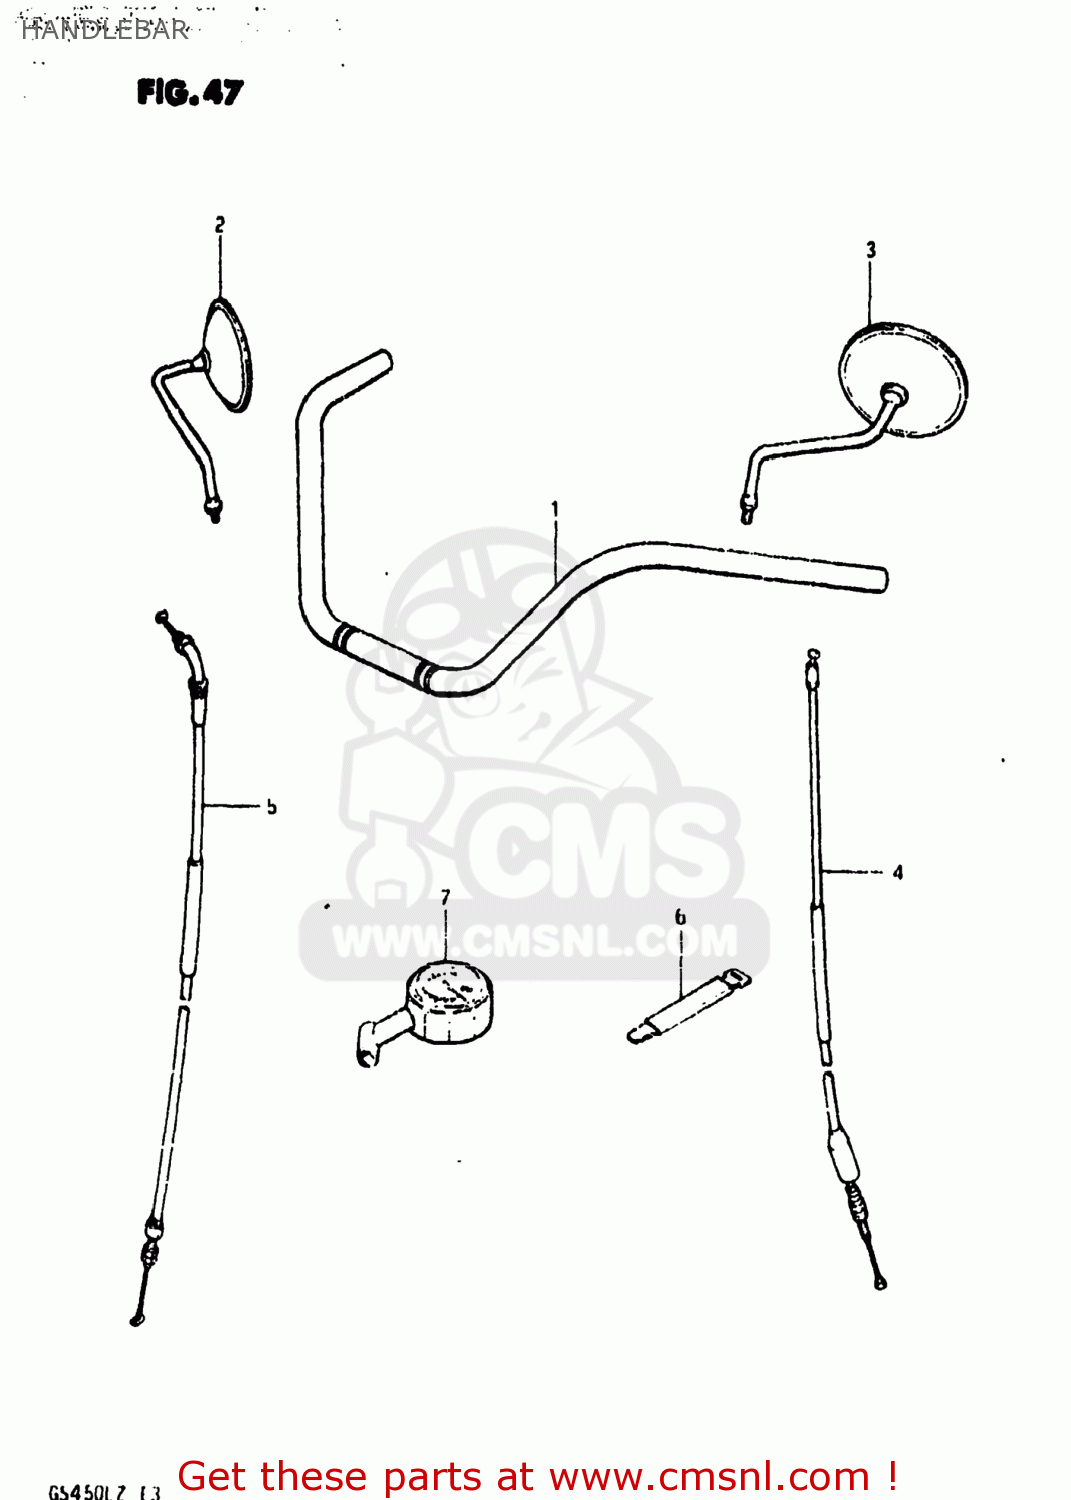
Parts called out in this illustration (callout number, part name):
1	HANDLEBAR
2	MIRROR ASSEMBLY,RIGHT
3	MIRROR ASSEMBLY,LEFT
4	CABLE ASSEMBLY,CLUTCH
5	CABLE ASSEMBLY,THROTTLE
6	CLAMP
7	GAUGE ASSY,AIR PRESSURE
